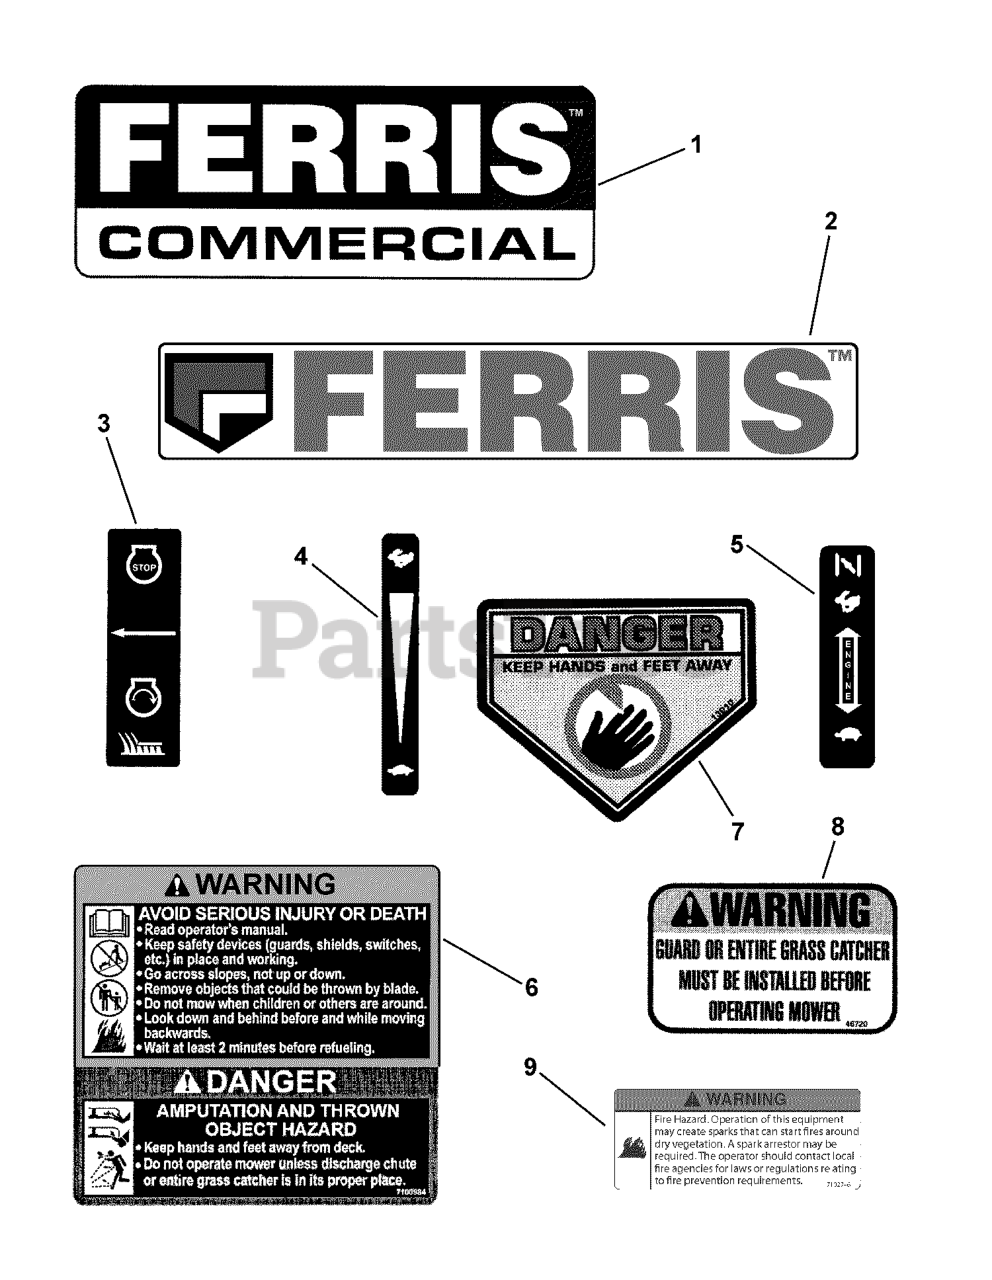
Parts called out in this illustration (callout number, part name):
1	DECAL, Control Panel, Ferris
2	DECAL, Deck, Ferris
3	DECAL, OPC Bail (International Symbol)
4	DECAL, Speed Shift
5	DECAL, Throttle Control, KWV
6	DECAL, Warning/Danger WBM
7	DECAL, Danger, Cut Finger
8	DECAL, Chute/Deflector
9	DECAL, Warning/Spark Arrestor
